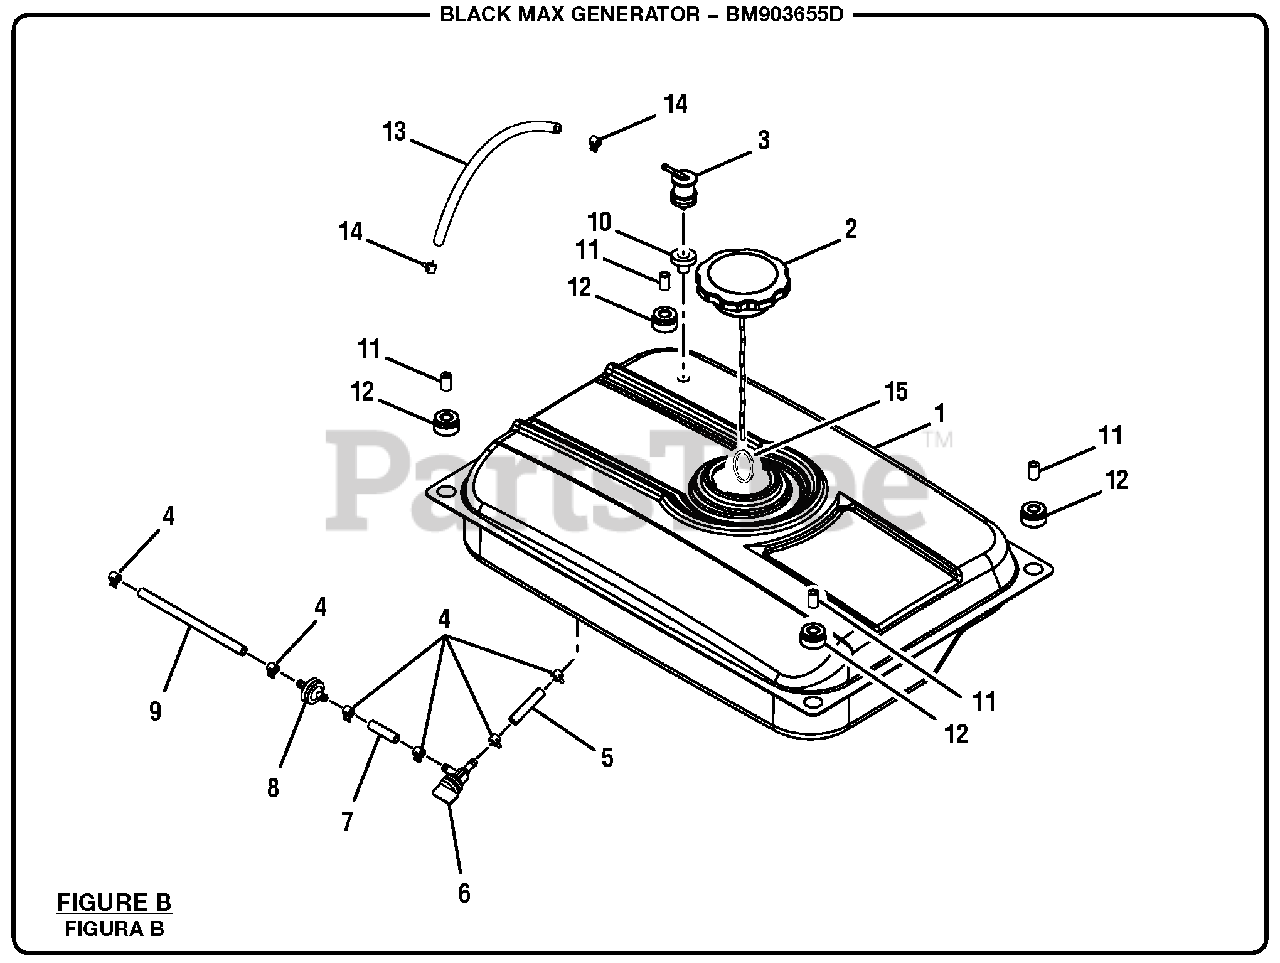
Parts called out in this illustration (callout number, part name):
1	Fuel Tank
3	Fuel Tank Vapor Vent
4	Clamp (1/2 in)
5	Fuel Hose (45 mm)
6	Fuel Shut Off Valve
7	Fuel Hose (35 mm)
8	Fuel Filter
9	Fuel Line (144 mm)
13	Vent Hose
14	Fuel Line Clamp (7/16 in)
15	Ring Clip
